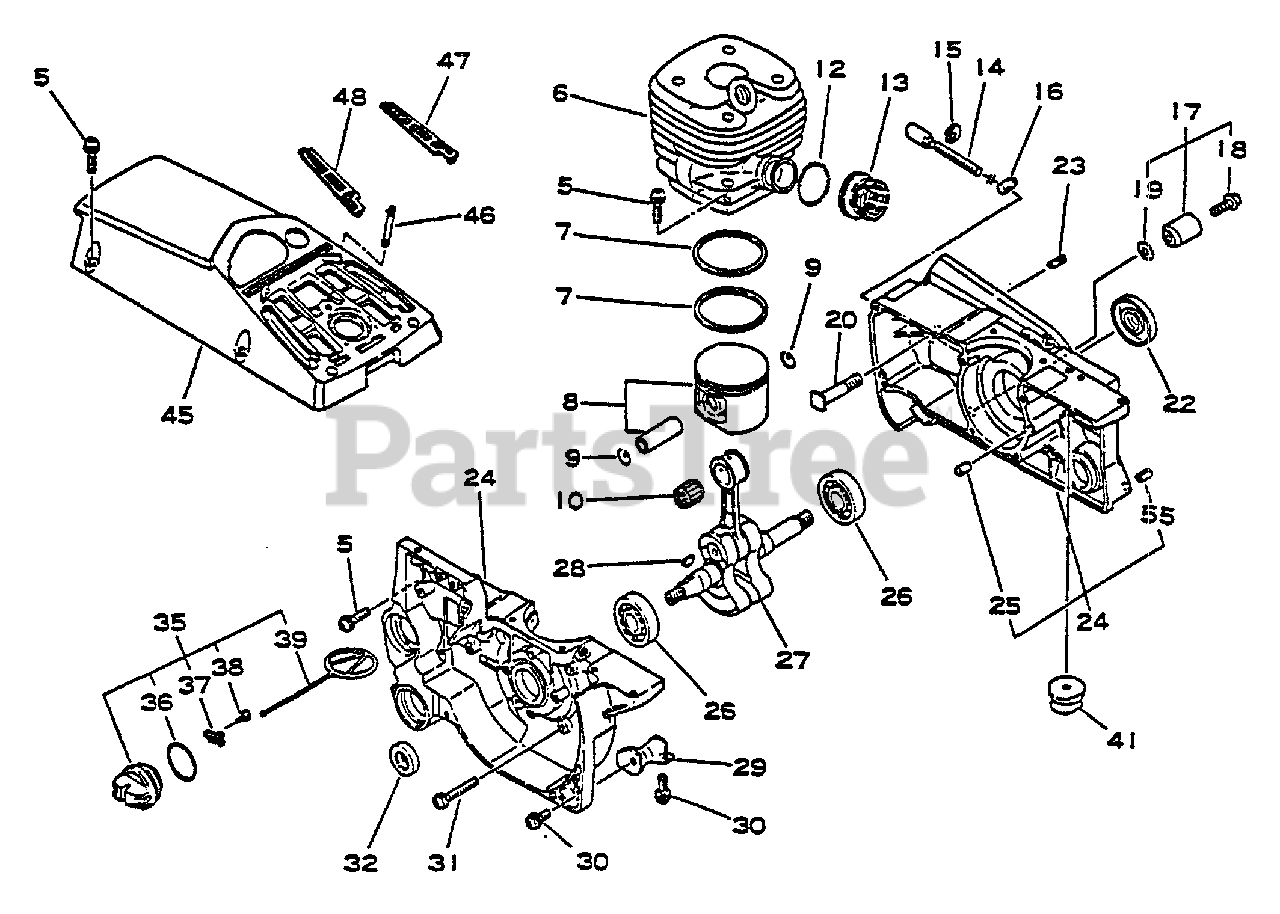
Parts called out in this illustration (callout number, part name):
5	SCREW 5×20
6	CYLINDER KIT
7	RING, PISTON
8	PISTON KIT
9	RING, SNAP
10	BEARING, NEEDLE
13	ADAPTOR, INTAKE
14	SCREW, ADJUSTER
16	TENSIONER, CHAIN
17	CHAIN CATCHER KIT
18	SCREW 5×20
19	WASHER, FLAT 5.5×10×0.8
20	STUD, GUIDE BAR 8
22	SEAL, OIL
23	VENT ASSY
24	CRANKCASE KIT
25	PIN, LOCATING 5×10
26	BEARING SET
27	CRANKSHAFT
28	KEY, WOODRUFF
30	SCREW 5×14
31	SCREW 5×35
32	SEAL, OIL
35	CAP ASSY
37	RETAINER, CONNECTOR
38	SCREW 3×8
39	CONNECTOR, CAP L= 60 MM
45	COVER, ENGINE
47	FILTER KIT
48	FILTER, AIR
55	PIN, SPRING 5×10
